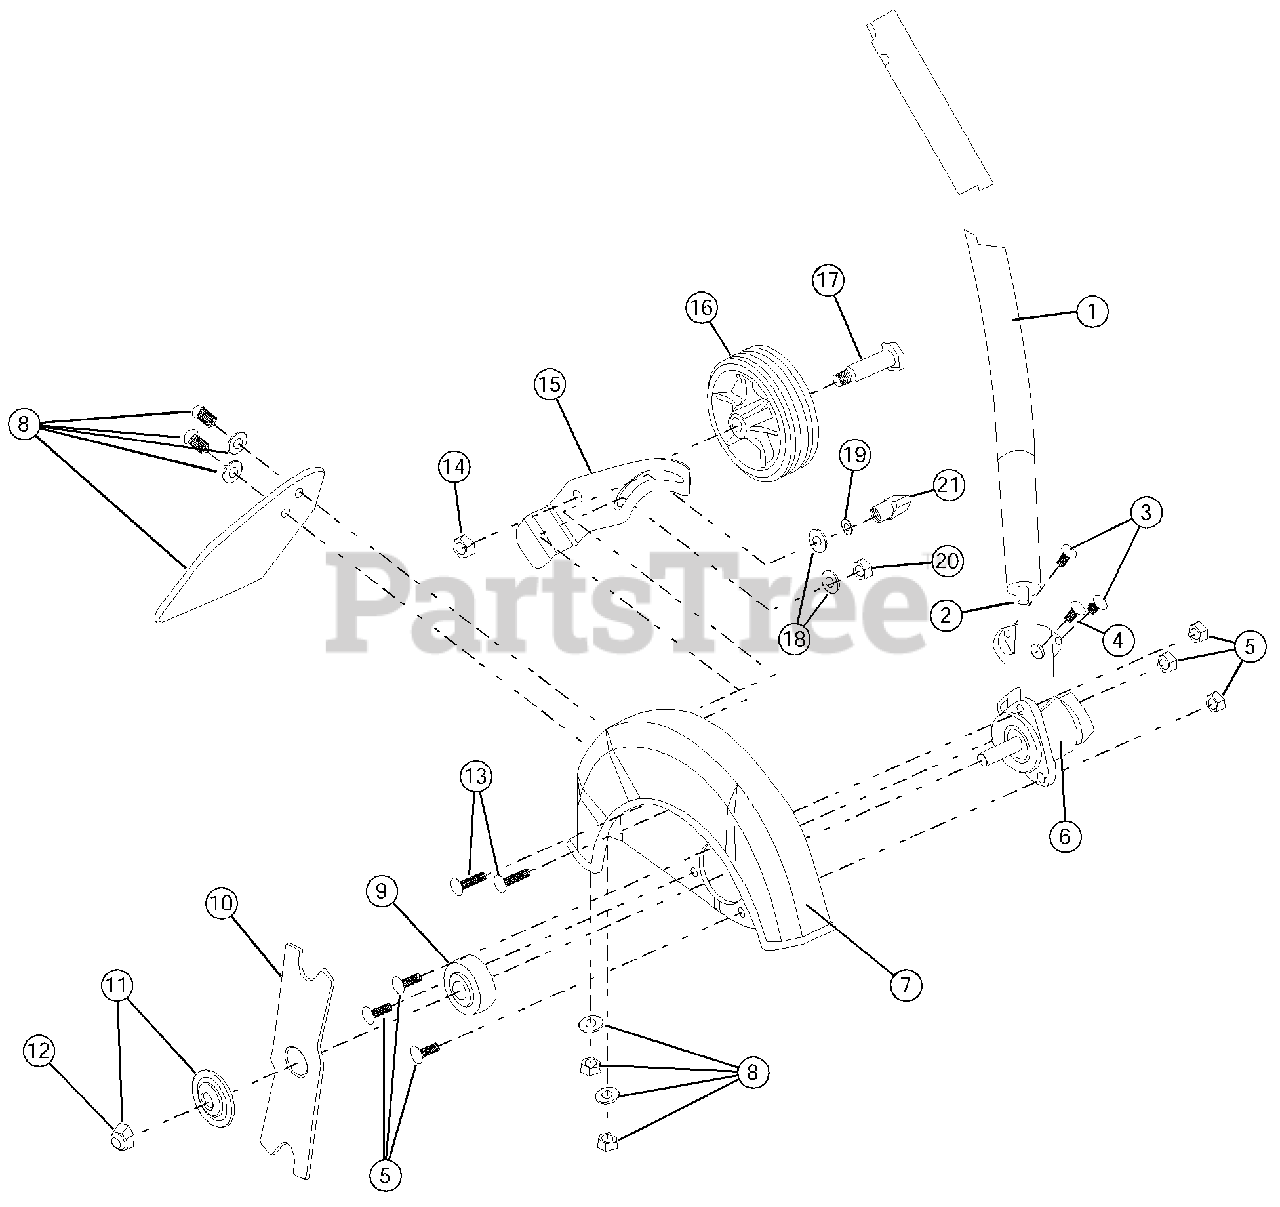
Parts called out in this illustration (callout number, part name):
1	Boom Assembly
2	Drive Shaft
3	Boom Mounting Hardware
4	Anti-Rotation Screw
5	Guard Mounting Hardware
6	Gearbox Assembly
7	Blade Guard
8	Deflector w/Hardware
9	Spacer
10	Blade
11	Blade Clamp Washer
12	Blade Retainer Nut
13	Wheel Bracket Mounting Bolt
14	Nut
15	Edger Guide
17	Shoulder Bolt
19	Washer
20	Nut
21	Edger Guide Knob
